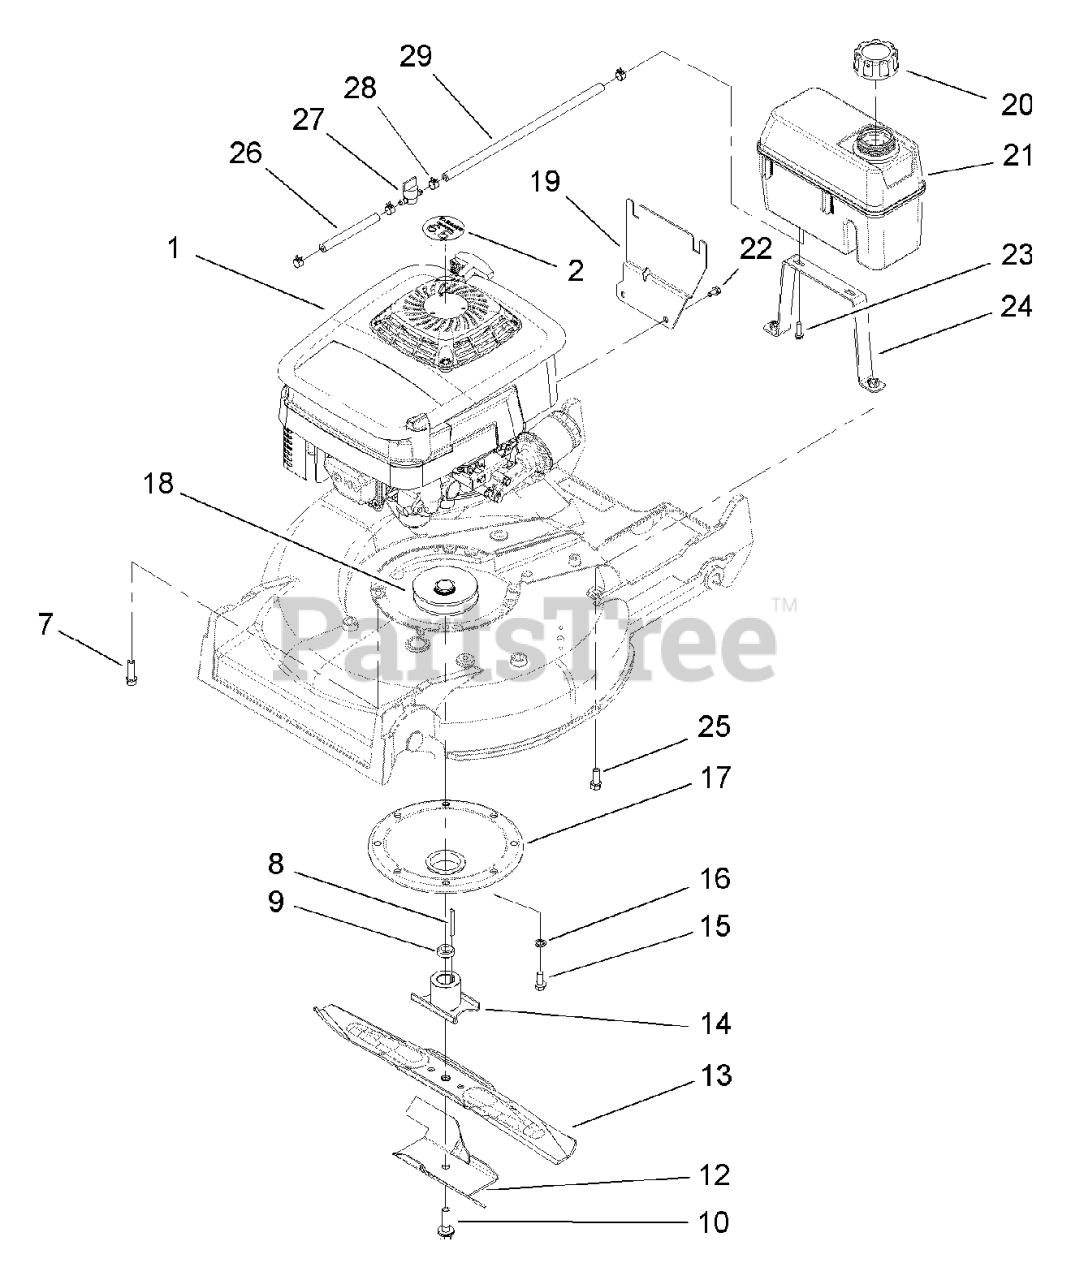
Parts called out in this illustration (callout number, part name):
2	Decal-Recoil
7	SCREW-TAPTITE
8	KEY-SQUARE
9	SPACER-RETAINER, BLADE
12	STIFFENER-BLADE
15	Screw-HWH 5/16-18 X 3/4 Tf
16	WASHER-LOCK, INTERNAL
18	PULLEY-DRIVER
19	BRACKET-TANK
20	CAP-GAS
22	SCREW-HWH
23	SCREW-HWH
25	SCREW-TAPTITE
27	VALVE-FUEL
28	CLAMP-HOSE
